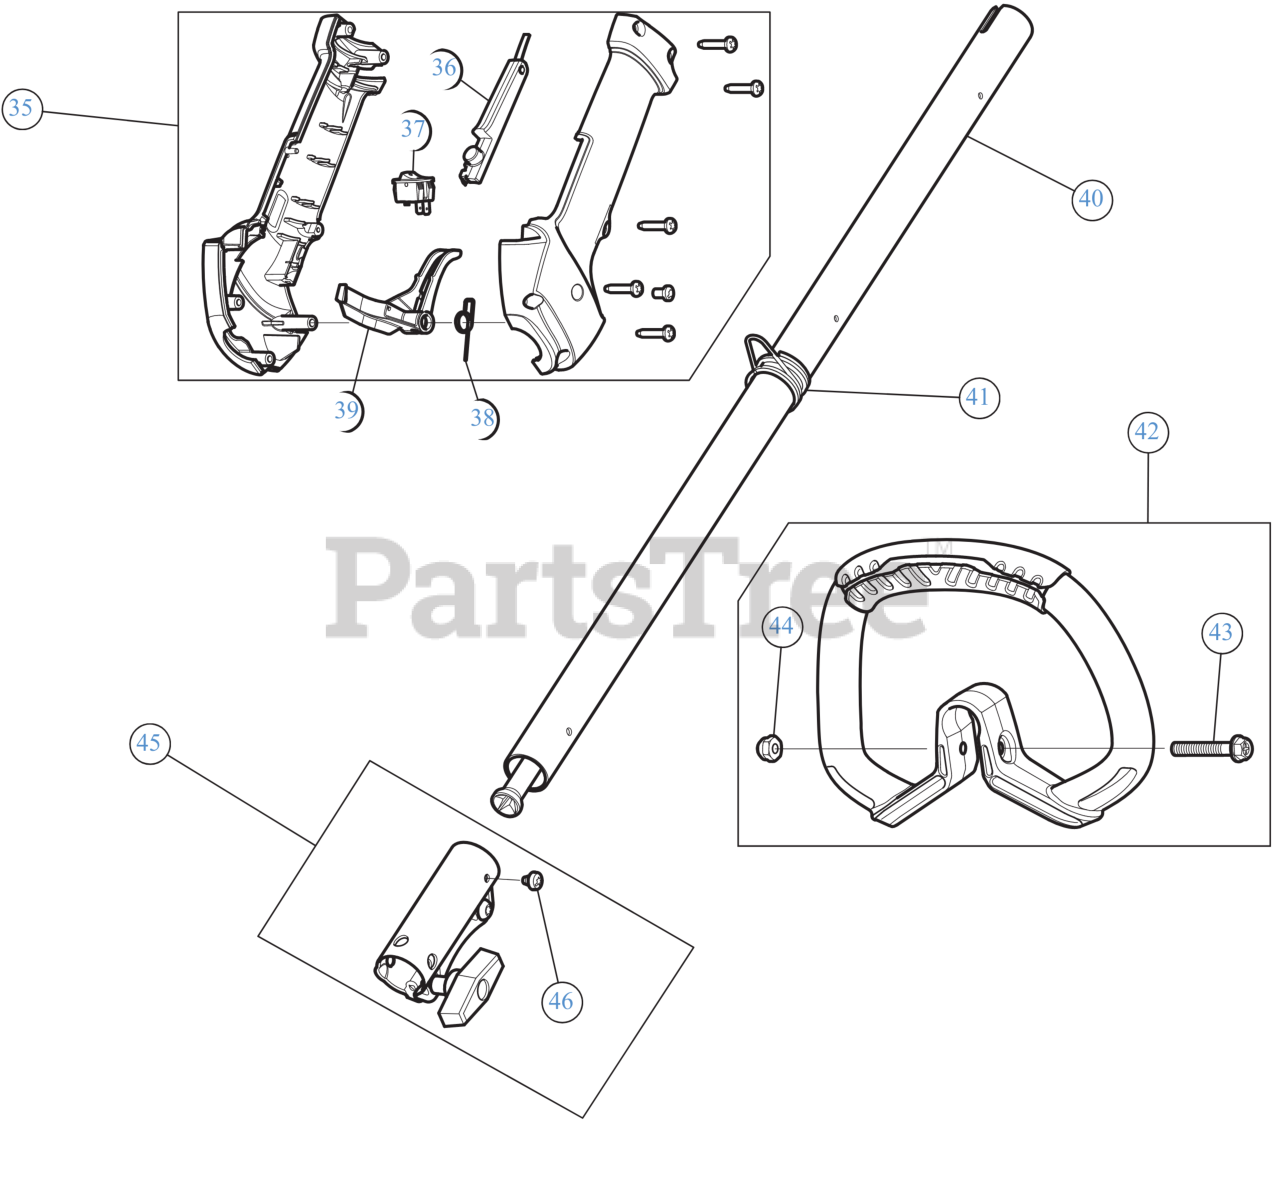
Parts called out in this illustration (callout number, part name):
35	THROTTLE GRIP ASSEMBLY
36	LEVER LOCK OUT
37	SW, MOMENTARY ON/O
38	TRIGGER SPRING
39	THROTTLE TRIGGER
40	UPPER SHAFT HOUSING
41	CLAMP-SHOULDER STR
42	HANDLE DLX
43	BOLT 1/4-20X1 1/2
44	NYLON LOCK NUT
45	COUPLER ASSEMBLY
46	SCREW, 10-32X.250 TA
